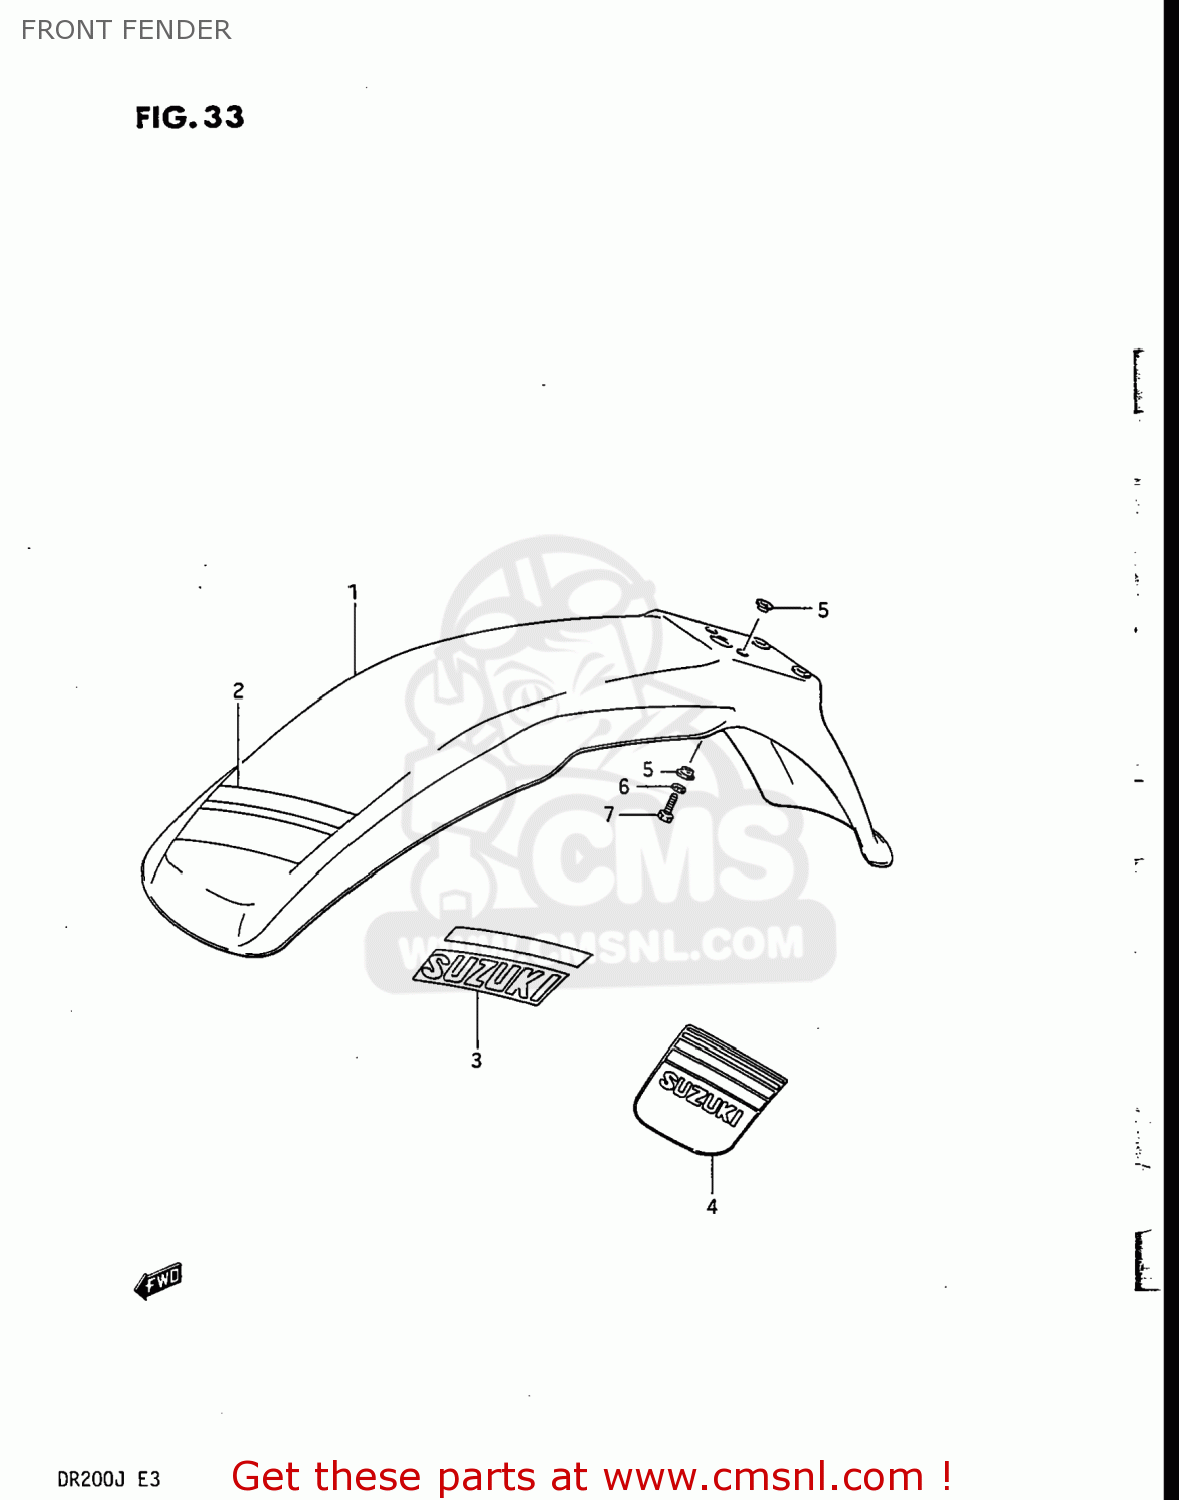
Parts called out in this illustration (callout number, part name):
1	FENDER,FRONT
2	TAPE SET,FRONT FENDER
3	TAPE,FRONT FENDER
4	TAPE,FRONT FENDER
5	WASHER
6	WASHER,LOCK
7	BOLT
